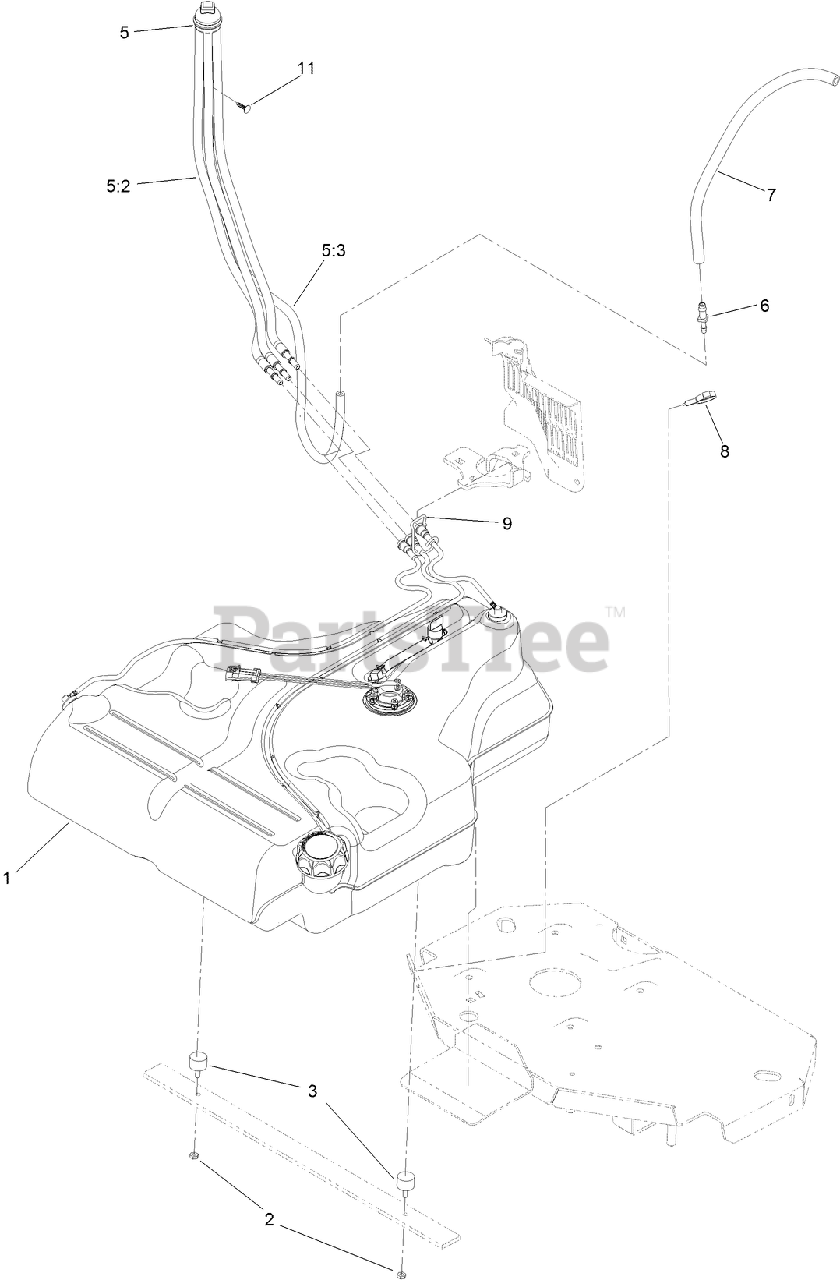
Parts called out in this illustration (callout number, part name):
1	FUEL TANK ASM
2	NUT-JAM
3	BUMPER
5	FUEL MANIFOLD VENT ASM
5:2	HOSE-FUEL
5:3	HOSE-FUEL
6	FITTING-STRAIGHT
7	HOSE-FUEL
8	CLAMP-HOSE
9	RETAINER-LINE, VAPOR
11	PLUG-PLASTIC
